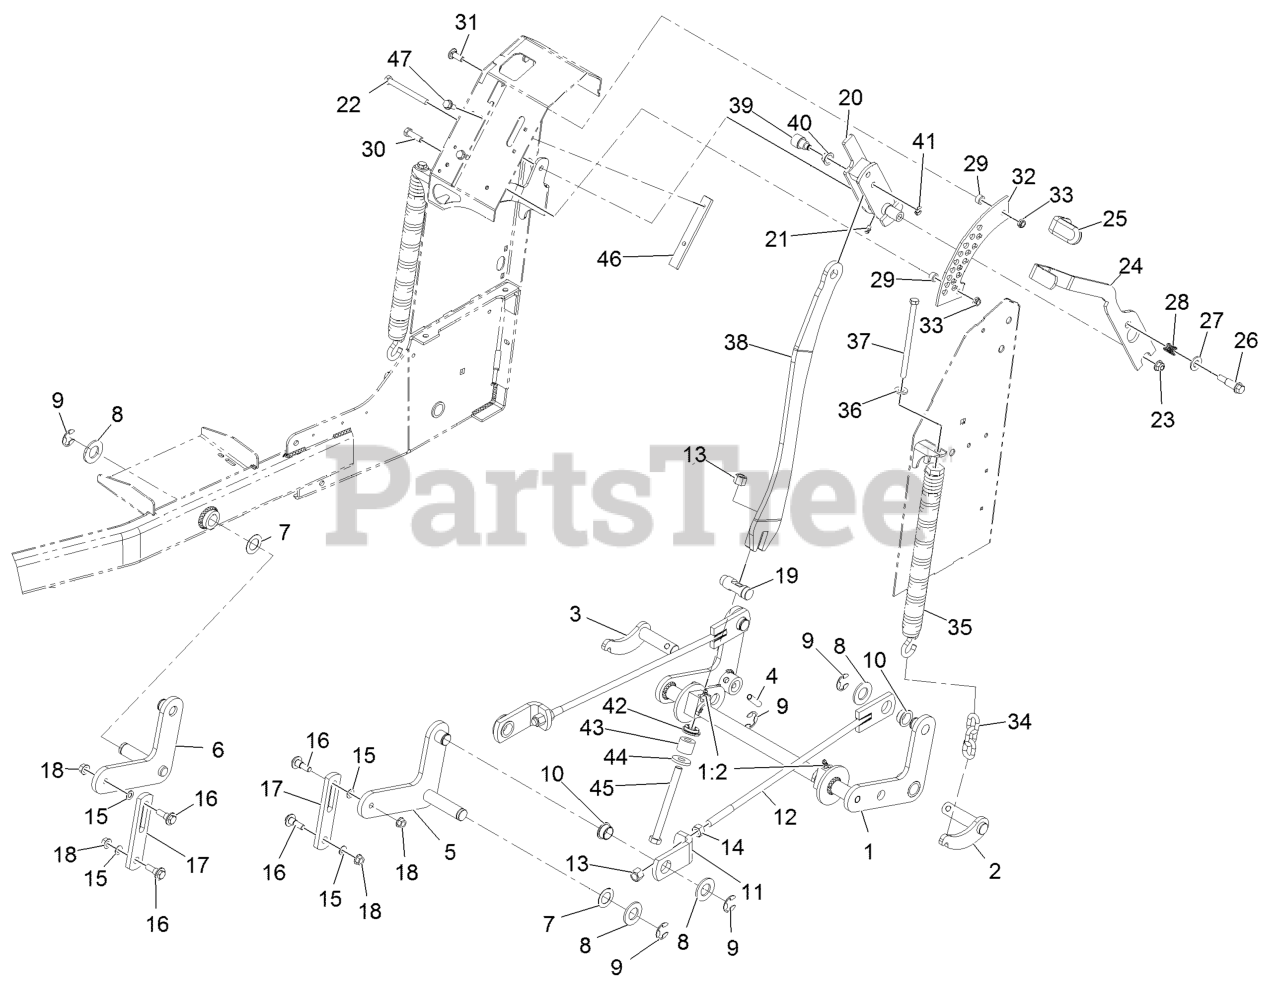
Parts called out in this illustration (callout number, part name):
1	REAR CROSSSHAFT ASM
1:2	FITTING-LUBE, 45 DEG
2	SHAFT-PIVOT, LH
3	SHAFT-PIVOT, RH
4	PIN-SPIRAL
7	WASHER-THRUST
8	WASHER-FLAT
9	RING-RETAINING, EXT
10	BEARING-FLANGE
11	BRACKET-LIFT ROD
12	LIFT ROD ASM
13	NUT-LOCK, NI
14	NUT-HH
16	SCREW-SHOULDER, HHF
17	LINK-LIFT
19	PIN-HOC
20	HOC HANDLE ASM
21	FITTING-GREASE
22	SCREW-HH
23	NUT-HF, NI
24	LEVER-HOC
25	GRIP-LEVER
26	SCREW-SHOULDER
27	WASHER-FLAT
29	SPACER
30	SCREW-HH
31	SCREW-CARR
32	BRACKET-HOC
34	CHAIN-DECKLIFT
35	SPRING-EXTENSION
36	WASHER-BELLEVILLE
37	BOLT-TAP, HH
38	BAR-LIFT
39	HUB-PIVOT
40	BEARING-FLANGE
41	RING-RETAINING
42	SEAT-SPRING
43	SPRING-URETHANE
45	SCREW-HH
46	SKID-HANDLE, LIFT
47	SCREW-THD ROLL, HWH
